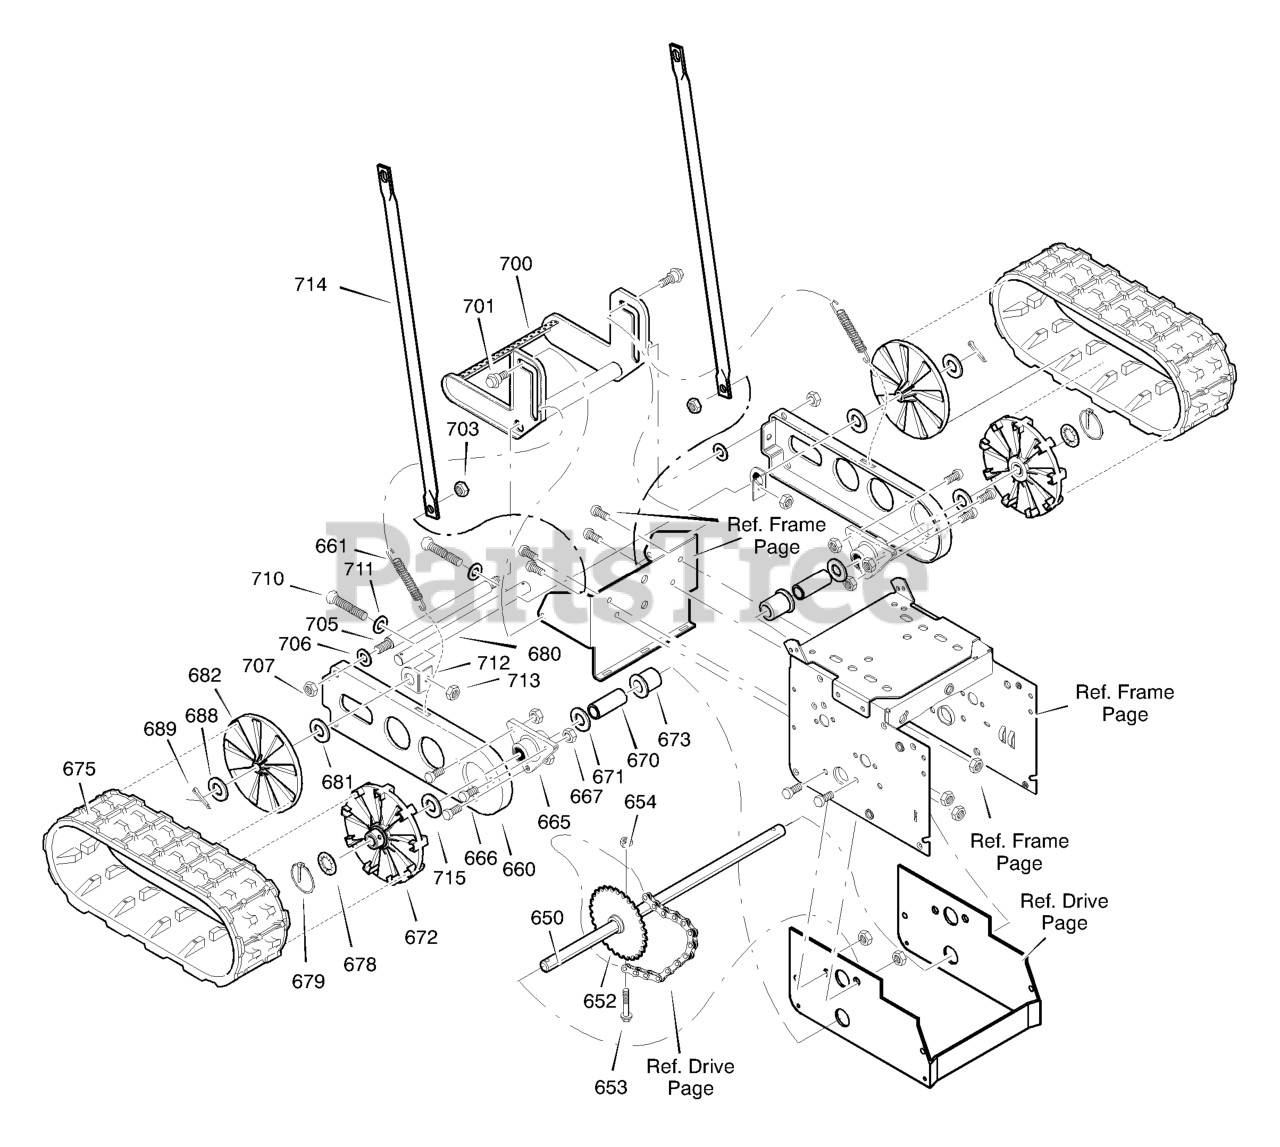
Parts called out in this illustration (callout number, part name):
650	SHAFT, AXLE
652	SPROCKET AND HUB
653	BOLT, HEX 1/4-20 x 2.25
654	NUT, 1/4-20
660	PLATE, TRACK DIRECT
661	SPRING, DRIVE IDLER
665	BEARING, TRACK
666	SCREW, 1/4-20 x075
667	NUT, 1/4-20
670	SPACER, .750 ID x 1.30
671	WASHER, FLAT
672	WHEEL, TRACK DRIVE 0.75 ID x 8.5 OD
673	BEARING, AXLE
678	RING, RETAINER
679	PIN, KLIK
680	SHAFT, IDLER
681	WASHER, FLAT
682	WHEEL, TRACK IDLER, 0.63 ID x 8.50 OD
688	WASHER, FLAT
689	PIN, COTTER
700	PEDAL, FOOT
701	BOLT, .430 x .265
703	NUT, 5/16-18
705	SHAFT, FOOT PEDAL -4.75"
706	WASHER, FLAT
707	NUT, 3/8-16
710	SCREW, 1/4-20 x 3.00
711	WASHER, FLAT
712	BRACKET, TRACK TENSIONER
713	NUT, 1/4-20
715	WASHER
